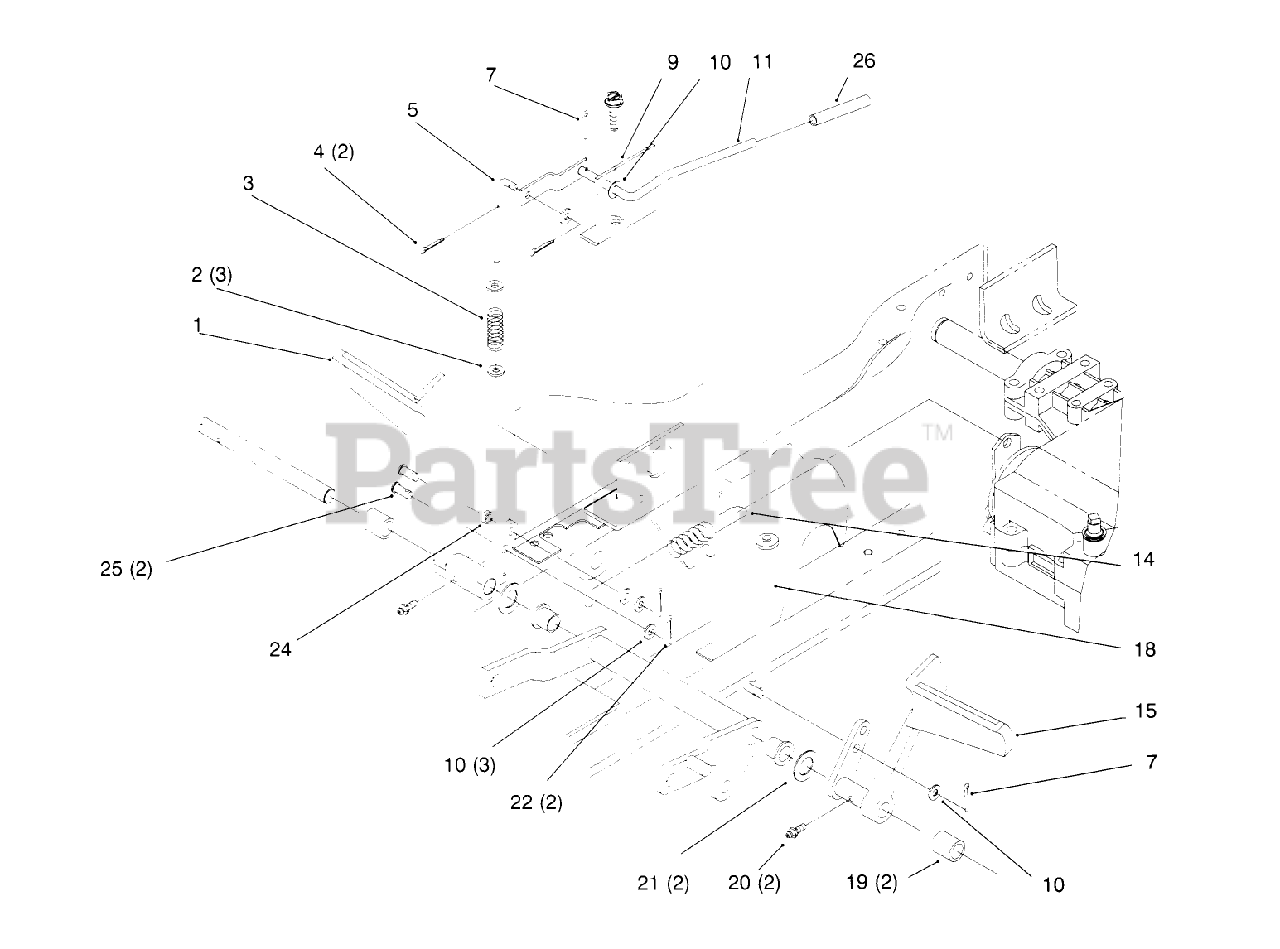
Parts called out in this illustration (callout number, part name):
2	WASHER-FLAT
4	PIN-COTTER
5	ROD - PARKING BRAKE
7	PIN-COTTER
10	WASHER-PLAIN
11	PARK BRAKE LVR WA*B
15	PEDAL-CLUTCH
18	CLUTCH ROD WA
19	SPACER
20	FITTING-GREASE
21	WASHER-WAVE
22	PIN-COTTER
24	BUSHING
25	PIN-CLEVIS
26	GRIP - PARKING BRAKE
